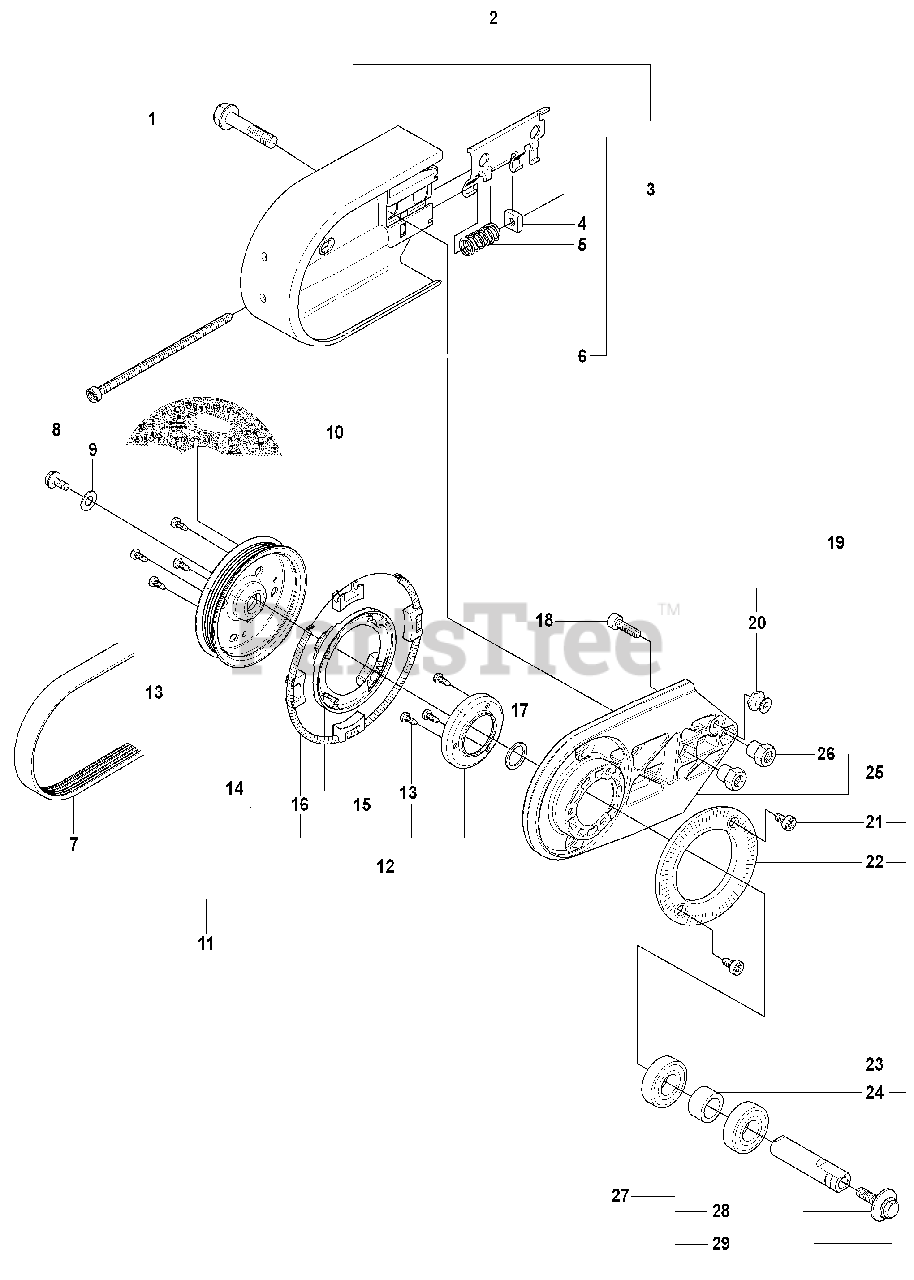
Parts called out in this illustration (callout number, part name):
1	COLLAR SCREW
2	BELT GUARD
3	BELT TENSIONER ASSY
5	COMPRESSION SPRING
7	BELT
9	WASHER STEEL
11	PULLEY
12	PULLEY
14	PULLEY
15	BRAKE SHOE
16	DRAW SPRING
17	WASHER STEEL
19	BEARING HOUSING
20	TORSION STOP
22	SCREEN PATTERN FLANG
23	BALL BEARING
24	SPACING SLEEVE
25	BEARING HOUSING
27	SHAFT
28	WASHER
29	COLLAR SCREW
